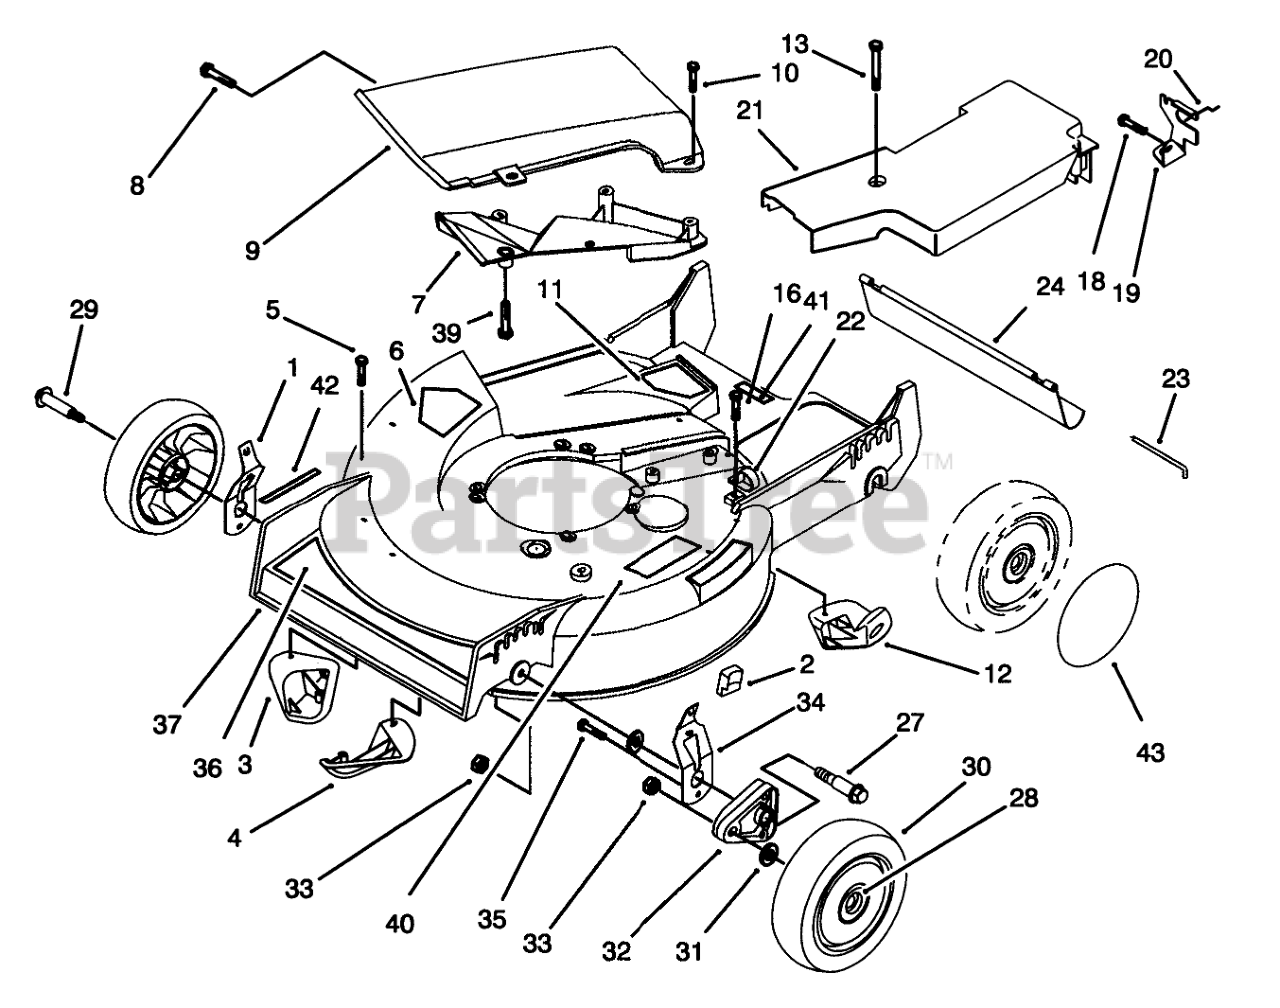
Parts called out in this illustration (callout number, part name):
1	RH SPRING ARM ASSEMBLY
2	KNOB-ARM
3	KICKER-FRONT
4	KICKER-RH
5	SCREW-PPH
6	DECAL-DANGER
7	Deflector-Recycler
8	SCREW AND WASHER ASM
9	Recycler Cover Assembly (Incl. Ref. #7 & 39)
10	SCREW-HWH
11	DECAL - DANGER
12	KICKER-REAR
13	SCREW-HHFTF
18	SCREW-HWHTF
19	Bracket-Adj. Trac
20	RETAINER-CABLE
21	BELT COVER
22	CLAMP-R
23	ROD-SHIELD
24	SHIELD-TRAILING
27	BOLT-SHOULDER
28	BUSHING
29	BOLT-WHEEL
30	Wheel & Tire Assembly (Incl Ref. #28)
31	WASHER
32	ARM-PIVOT, FRONT
33	NUT-LOCK
34	LH SPRING ARM ASSEMBLY
35	SCREW-HWH
36	DECAL - DECK
37	Housing (Incl. Ref. #3-6, 11, 12, 18 & 40-42)
39	Screw-Plastite
40	DECAL-INSTRUCTION, SAFETY
41	DECAL-WARNING
42	DECAL - HOC
43	WHEEL COVER
